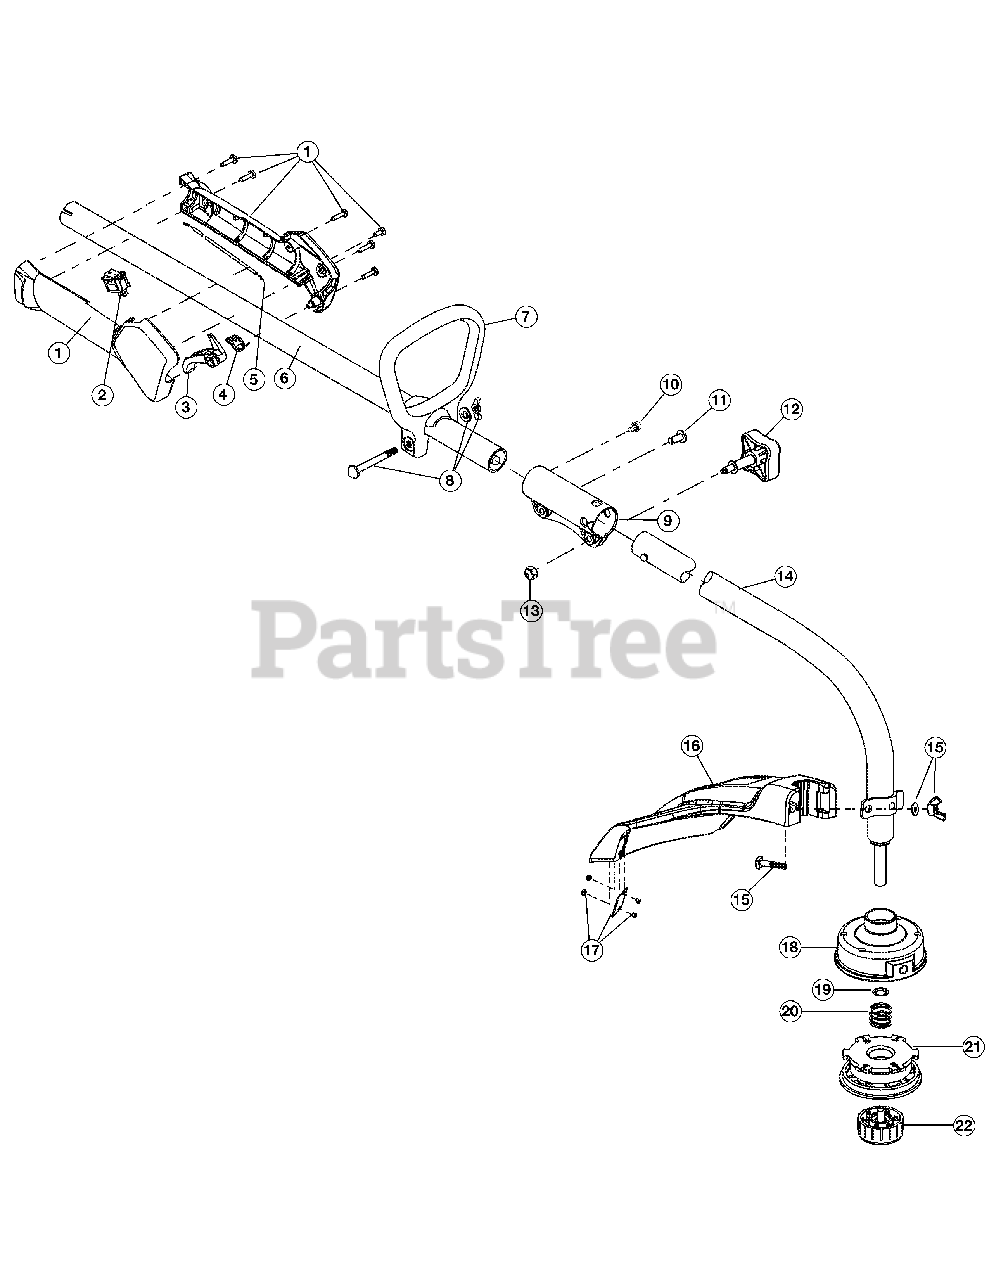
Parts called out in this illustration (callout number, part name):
1	Throttle Housing Assembly (includes 2-4)
3	Throttle Trigger
4	Throttle Trigger Spring
5	Throttle Cable
6	Upper Drive Shaft Housing Assembly
7	D-Handle (includes 8)
8	Handle Hardware
9	Split Boom Coupler (includes 10-13)
12	Adjustment Knob
13	Knob Retaining Nut
14	Lower Drive Shaft Housing Assembly
15	Guard Mounting Hardware
16	Guard (includes 15)
17	Blade Assembly
18	Outer Spool Assembly (includes 19)
19	Retainer
21	Inner Reel
22	Bump Head Knob Assembly
